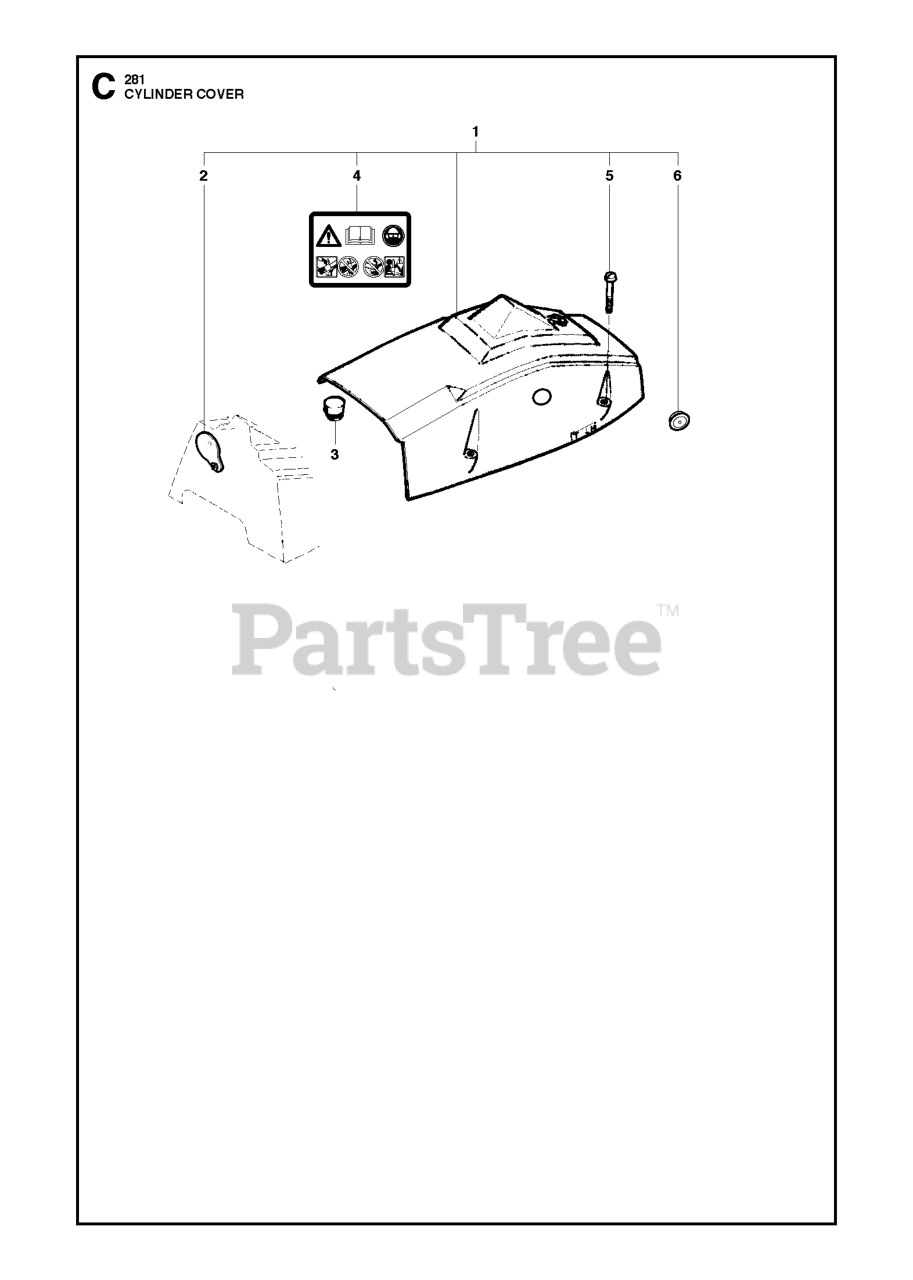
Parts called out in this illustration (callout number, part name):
1	CYLINDER COVER USA
2	COVER
3	RUBBER BUMPER
4	DECAL
6	PLUG
